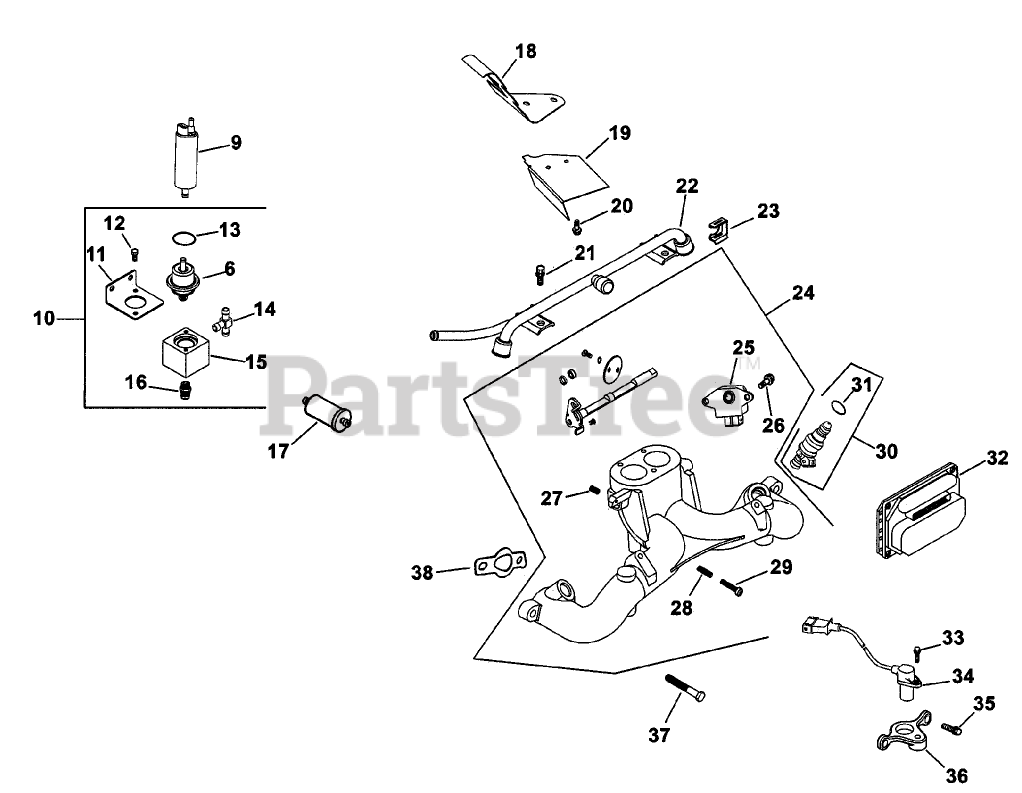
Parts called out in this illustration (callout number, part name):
6	Regulator-Pressure
9	Fuel Pump ASM
10	Regulator ASM, Pressure (Incl.6,11-16)
11	Bracket-Regulator,Horizontal
12	Screw-HH
13	O-Ring
14	Fitting-Tee
15	Housing-Regulator,Horizontal
16	Connector-Hose, Straight
17	Filter-Fuel
18	Baffle-Valley
19	Deflector-Air
20	SCREW-HHFTF (M5X.80X10)
21	Screw-HF (M6x1.0x10)
22	Rail-Fuel
23	Clip-Injector, Fuel
24	Manifold ASM, Intake (Incl. 25-29 & 24 176 77-S)
25	Sensor-Position,Throttle
26	Screw-Head, Pan
27	Spring, Idle Bump
28	Spring-Control, Speed
29	Screw-HH
30	Injector, Fuel (Incl. 31)
31	O-RING
32	Module-Management,Ignition
33	Screw-HF
34	Sensor-Speed, Engine
35	SCREW-FLANGE, THREAD FORMING (M5X0.8X16)
36	Bracket-Sensor,Speed
37	Screw-HF
38	Gasket-Manifold, Intake
